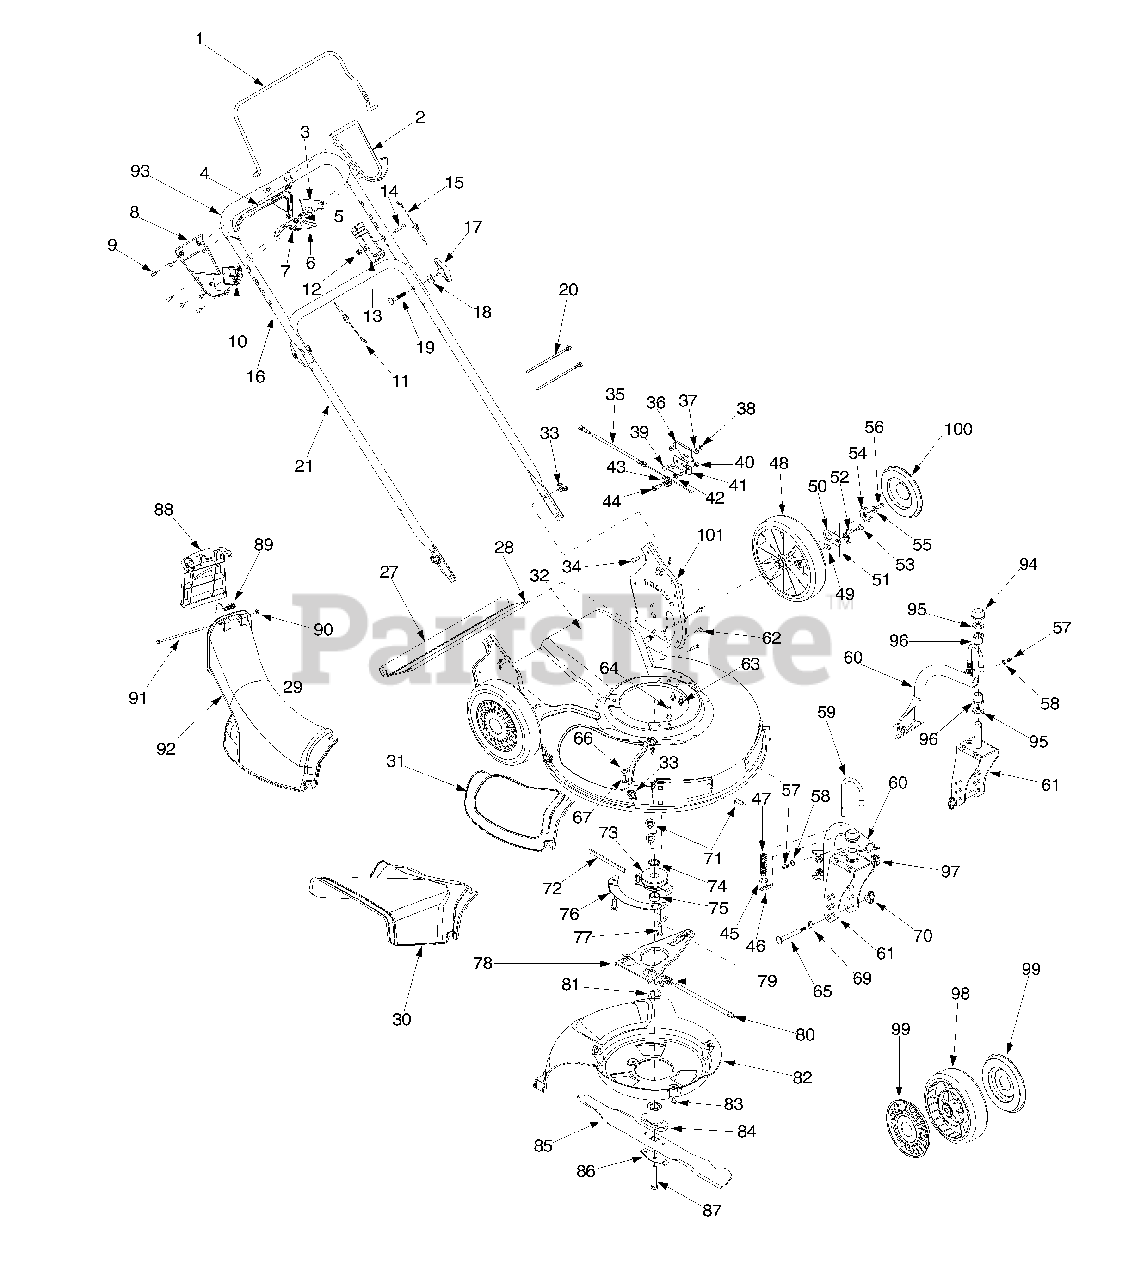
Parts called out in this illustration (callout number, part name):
1	Control Handle
2	Upper Control Handle
3	6 Spd. Rack Cable Bracket
4	Control Lever
5	Gear Insert
6	Shift Lever Spring
7	6 Speed Shift Lever
8	Lower Control Housing
9	C Sunk Tap Screw #10 x .75 Lg
10	Cable Mounting Cap
11	Drive Cable 51.0
12	Top Lock Nut 1/4-20
13	Control Housing
14	Oval C-Sunk Screw
15	Control Cable 46"
17	Wing Nut
18	Saddle Washer .320 ID x .830 OD
19	Carriage Bolt 5/16-18 x 2.0
20	Cable Tie
27	Trail Shield
28	Trail Shield Wire
29	Chute Assembly
30	Side Discharge Chute
31	Mulch Cover
34	Carriage Bolt 1/4-20 x .75
35	6 Speed Cable
38	Hex Nut 1/4-20
39	Carriage Screw 1/4-20 x .50
40	Hex Nut 1/4-28
43	Roller Cable
44	Shoulder Screw .375 ID x 1/4-14
45	Flat Washer .330 ID x .630 OD
46	Cotter Pin
47	Compression Spring
48	Wheel 9 x 2
49	Top Lock Tab Weld Nut 1/4-20
50	Ratchet Pawl Plate
51	Plastic Spring Ratchet
53	Shld Screw .340 ID x .285 OD
54	Wheel Rachet
55	Bell Washer .265 ID x .75 OD
56	Hex Cap Screw 1/4-20 x .620
57	Grease Fitting
58	Flat Washer .203 ID x .403 OD
59	Wheel Pin Lock
62	Screw 1/4-14 x .500
63	Screw 1/4-14 x .625
64	Hex Washer Screw 3/8-16 x 1.0
65	Caster Axle
66	Flat Washer .344 ID x .62 OD
67	Carriage Screw 1/4-20 x .75
69	Wave Washer .531 ID x .781 OD
70	Wing Nut
71	Carriage Bolt 5/16-18 x .62
72	Belt 3/8 x 39.24
73	Pulley Assembly
74	Sleeve Spacer .88 ID x 1.13 OD
75	Sleeve Spacer .88 ID x 1.00 OD
77	Screw 3/8-18 x 1.0
80	Pivot Shaft
81	Wave Washer 1.38 ID x .88 OD
82	Baffle
83	Screw 1/4-20 x 3.75
84	Blade Adapter Kit
85	21" Mulching Blade
86	Blade Bell Support
87	Hex Bolt 3/8-24 x 2.5
88	Chute Door
89	Torsion Spring
91	Pivot Rod
92	Discharge Chute
93	Grip
95	Flat Washer 640 ID x 1.12 OD
96	Flange Bearing
97	Flange Lock Nut 5/16-18
98	Wheel 7 x 2
99	Hubcap - Spoke w/ Hole
100	Hubcap - Radial Spoke
